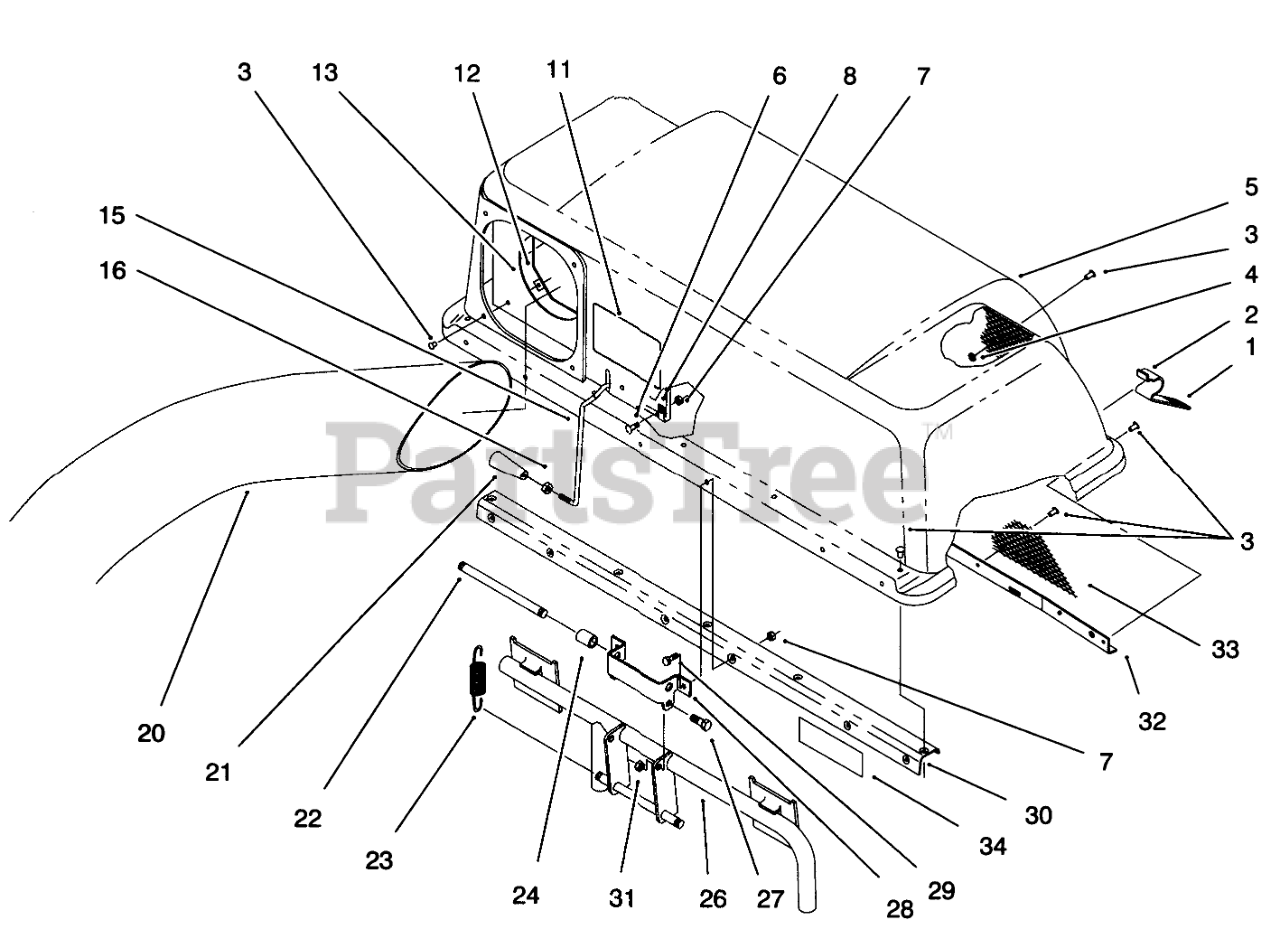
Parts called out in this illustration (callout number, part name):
2	Latch-Bag
3	RIVET-BLIND
4	WASHER-FLAT
5	TOP-BAGGER
6	SCREW-PPH
7	NUT-LOCK, NI
8	CLAMP
11	DECAL
12	CLAMP-SEAL
13	SEAL-CHUTE
15	FEELER-FILL, BAG
16	NUT-JAM
20	CHUTE-BAGGER
21	HANDLE-TAPERED
22	PIN-SPRING
23	SPRING-EXTENSION
24	Spacer
26	FRAME ASM
27	SCREW-HH
28	HINGE-BAG TOPB
29	SCREW-HH
30	Bagger-Stiffener
31	NUT-LOCK, NI
32	Screen Support
33	SCREEN-BAGGER
34	Decal-Caution
